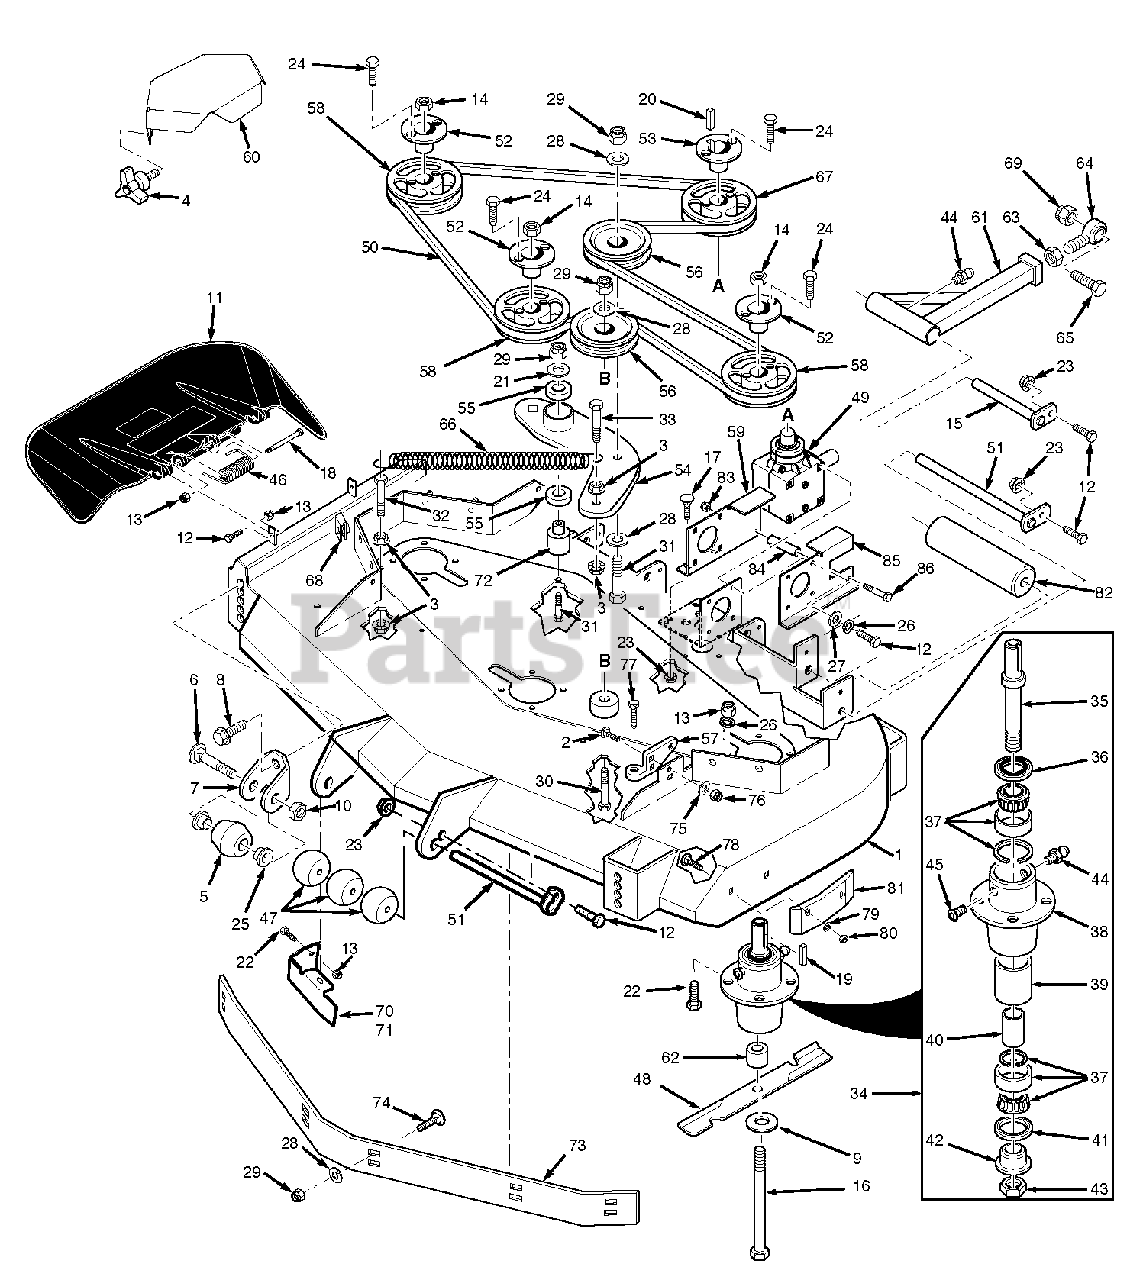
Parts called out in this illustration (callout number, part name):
1	Cutter Deck Velocity Plus
2	Bolt, Carriage 7/16-14 x 1-1/4"
3	Nut, Hex Serr. Flng 3/8-16
4	Wing nut, 3/8-16
5	Anti-Scalp Wheel
6	Bolt, Carriage 3/8-16 x 4"
7	Anti-Scalp Wheel Bracket
8	Bolt, Hex Serr. Flng 3/8-16 x 1"
9	Flatwasher, 5/8" Hardened
10	Locknut, 3/8-16 Center Lock
11	Discharge Chute Assembly
12	Bolt, Hex Head 5/16-18 x 1-3/4" - Front
12	Bolt, Hex Head 5/16-18 x 1-1/2" - Rear
13	Nut, Hex Elastic Stop 5/16-18 Grd 8
14	Nut, 5/8-11 UNC
15	Push Arm Shaft
16	Bolt, HH 5/8-11 x 9-1/2"
17	Bolt, Carriage 5/16-18 x 3/4"
18	Bolt, HH 5/16-18 x 4-1/2"
19	Key, 1/4 x 1/4 x 2"
20	Key, 1/4 x 1/4 x 1-1/4"
21	Flatwasher,3/8" (.39 x .938 x .105") HD
22	Bolt, HH 5/16-18 x 1-3/4"
23	Nut, Hex Serr. Flng 5/16-18
24	Bolt, HH 1/4-20 x 1" Grd 8
25	Bushing, .376" I.D. Oilite
26	Lockwasher, 5/16"
27	Flatwasher, 5/16" (.375 x .875 x .083")
28	Flatwasher, 3/8" (.391 x .938 x .105")
29	Nut, Hex Elastic Stop 3/8-16
30	Bolt, HH 3/8-16 x 3-1/4"
31	Bolt, HH 3/8-16 x 3"
32	Bolt, HH 3/8-16 x 1-1/2"
33	Bolt, HH 3/8-16 x 1-1/2" Grd 8
34	Spindle Assembly
35	Spindle Shaft
36	Seal, Top
37	Bearing Assembly
38	Spindle Housing
39	Spacer, Outside
40	Spacer, Inside
41	Seal, Bottom
42	Spindle Bushing, Bottom
43	Nut, Special 1-1/16-18
44	Grease Fitting
45	Relief Fitting, Tapered Spindle
46	Spring, Discharge Chute
47	Wheel, Anti-Scalp
48	Cutter Blade, 18"
49	Gearbox Assm, Deck Drive
50	Belt, Cutter Deck Drive
51	Roller Shaft
52	Tapered Hub, 1-1/8" Bore
53	Tapered Hub, 1" Bore
54	Idler Arm, Cutter Deck
55	Bearings, Ball
56	Pulley, Idler
57	Lever Assembly, Deck Level
58	Pulley, 5.75" O.D. (52")
59	Mounting Plate, RH Gearbox
60	Belt, Cover (52)
61	Pusharm
62	Spacer, Spindle Bottom
63	Nut, Hex Head 5/8-18 UNF
64	Rod End, 5/8" Male RH Thrd
65	Bolt, Hex Head 5/8-11 x 4-1/2"
66	Spring, Cutter Deck
67	Pulley, 6.95" O.D.
68	U-Nut, 3/8-16
69	Nut, Hex Elastic Stop 5/8-11
71	Turbo Baffle, 52V
72	Pivot, Idler
73	Baffle, Custom Cut 52V
74	Bolt, Carriage 3/8-16 x 1"
75	Flatwasher, 7/16" (.500 x 1.25 x .083")
76	Nut, Elastic Stop 7/16-14
77	Bolt, Deck Adjust
78	Bolt, Carraige 5/16-18 x 3/4"
79	Flatwasher, 5/16"
80	Nut, Center Lock 5/16-18
81	Wear Pad
82	Wheel, Anti-Scalp
83	Nut, Elastic Stop 5/16-18
84	Spacer, Gearbox Mount
85	Mounting Plate, LH Gearbox
86	Bolt, HH 5/16-18 x 4-3/4"
